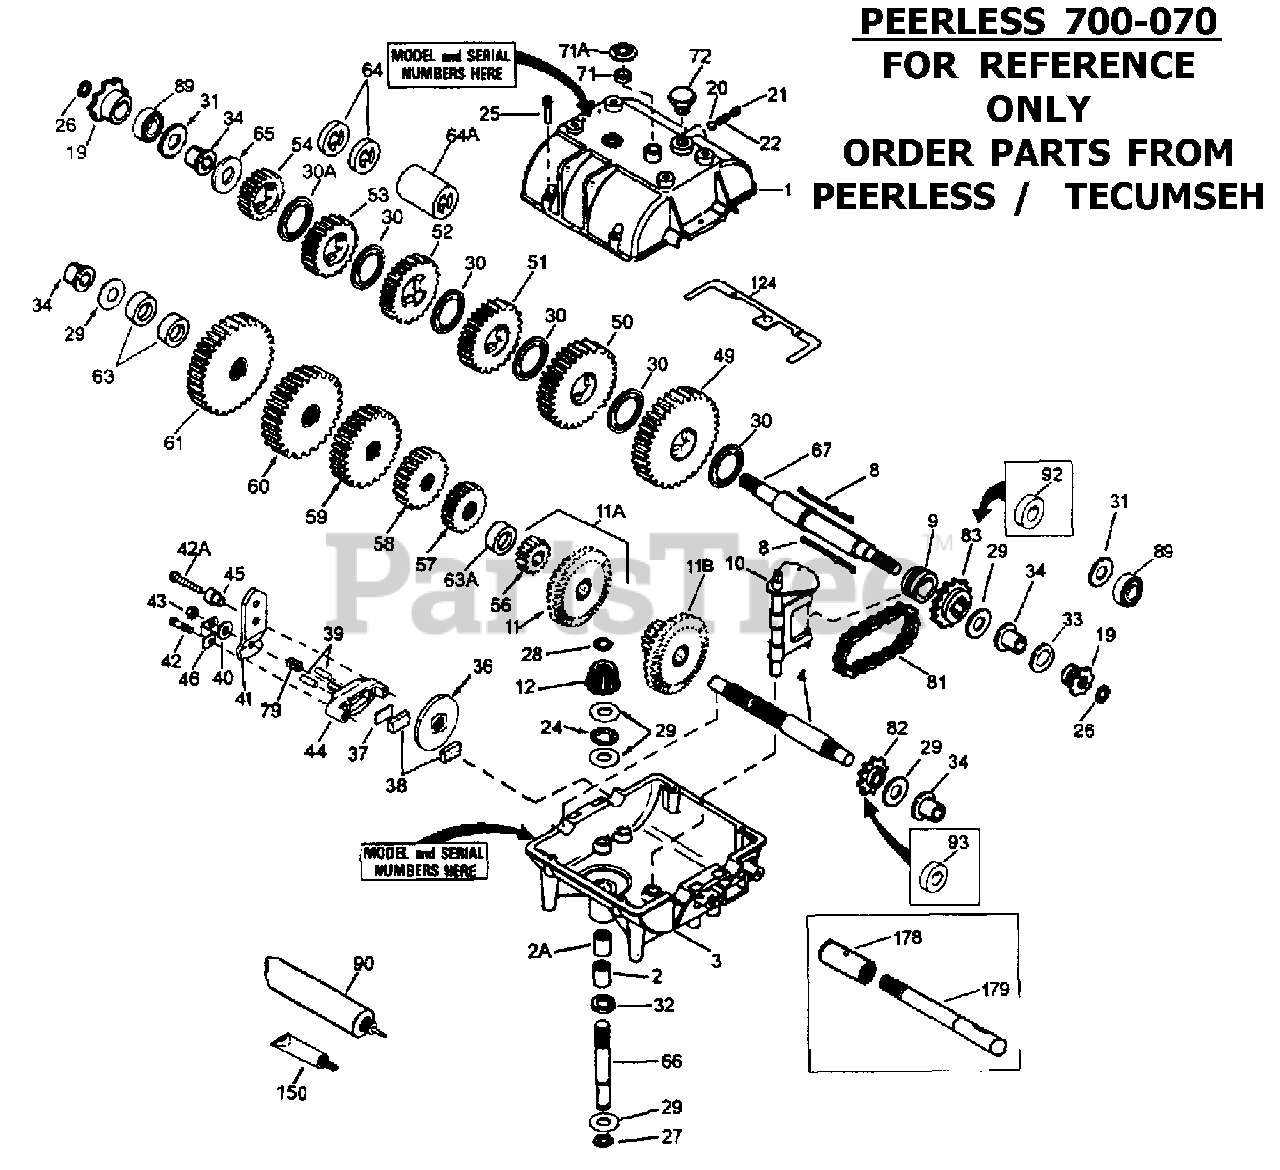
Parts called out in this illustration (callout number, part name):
1	Case, Transmisson
2	Needle Bearing Grease Spec
2A	Needle Bearing
3	Case, Transmission
8	Shift Key
9	Shift Collar
10	Shift Rod & Fork
11	Bevel Gear (42 teeth)
12	Bevel Pinion (14 teeth-steel)
20	Steel Ball, 5/16" dia.
21	Set Screw, 3/8-16 x 3/8"
22	Spring
24	Thrust Bearing
25	Screw, 1/4-20 x 1-1/4"
27	Retaining Ring
28	Retaining Ring
29	Washer
30	Washer
32	110" Ring
34	Flanged Bushing
49	Spur Gear (37 teeth)
50	Spur Rear (35 teeth)
51	Spur Gear (32 teeth-steel)
52	Spur Gear (30 teeth)
53	Spur Gear (25 teeth)
56	Spur Gear (12 teeth-steel)
57	Spur Gear (15 teeth)
58	Spur Gear (18 teeth-steel)
59	Spur Gear (20 teeth)
60	Spur Gear (25 teeth)
65	Washer
66	Input Shaft (3-11/16" long)
67	Shifter & Brake Shaft
71	Square Cut Ring
72	Threaded Plug
81	Roller Chain
82	Sprocket (9 teeth)
83	Sprocket (18 teeth)
90	Grease (32 oz. bottle Bentonite grease)
150	Gasket Eliminator (Loctite #515)
178	Coupling
179	Connector Shaft
